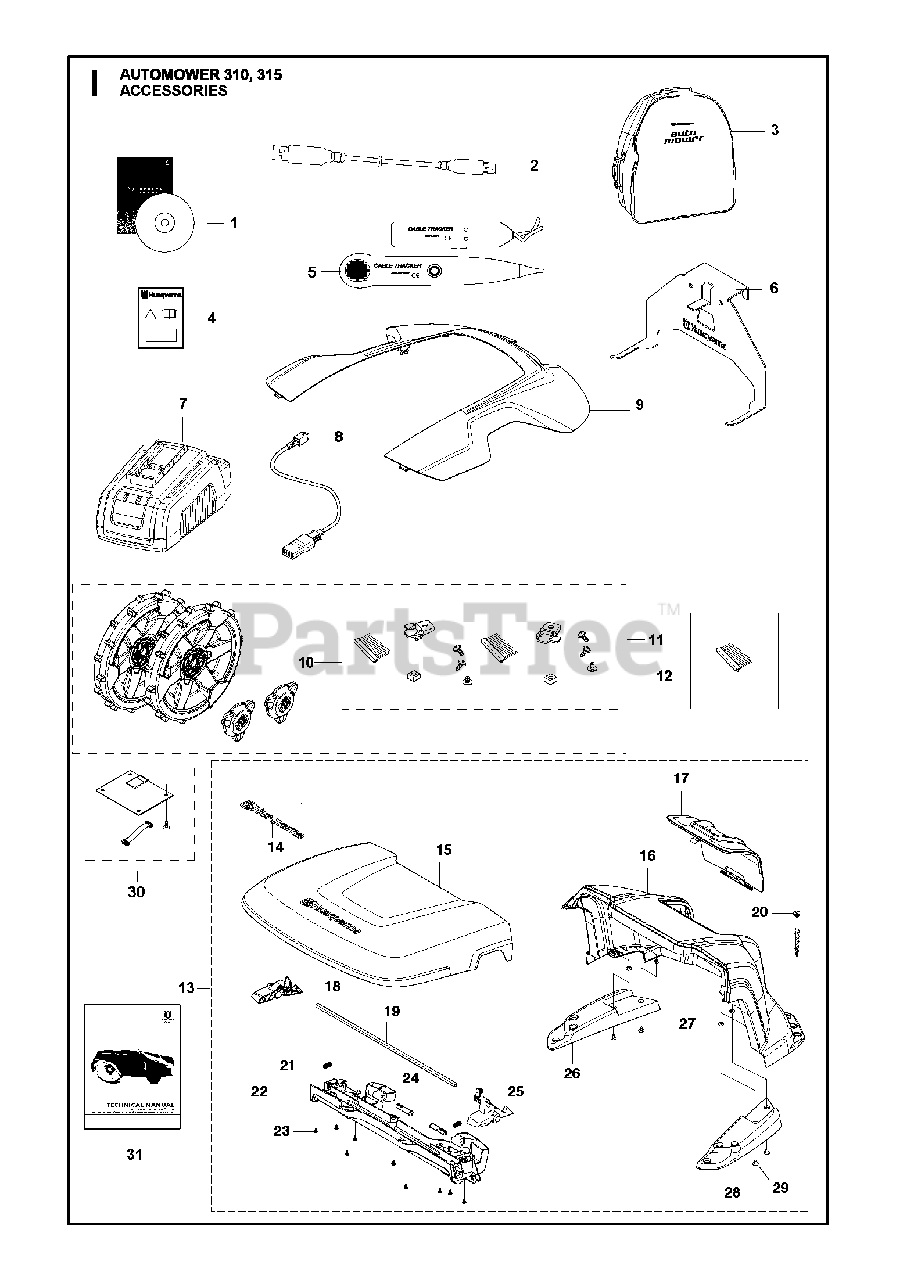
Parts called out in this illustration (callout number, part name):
1	DVD Autocheck, Exp Ser
2	CABLE WHITE ALT GREY
3	BAG
4	LABEL WARRANTY SEAL DEALER
5	TEST EQUIPMENT
6	315 WALL HANGER
7	CHARGER BATTERY TEST
8	CABLE ASSY QUICK CHARGER
9	GREY COVER
9	Cover, White
9	ORANGE COVER
10	WHEEL BRUSH KIT 315
11	WHEEL KIT AM310315. H
12	BRUSH WITH CARTON
13	HOUSE KIT FOR 315
14	DECAL.HUSQVARNA.210MM
15	COVER LID 315
16	COVER BASE P15
17	HATCH
18	HANDLE RELEASE LEFT
19	ROD
20	SCREW KIT CS
21	SPRING SPRING CAP
22	BEAM
23	SCREW 14MM
24	HINGE PIN
25	HANDLE RELEASE RIGHT
26	SUPPORT BASE LEFT
27	NUT
28	SUPPORT BASE RIGHT
29	SCREW IHPANM M6X25 4.6 ZP-BC
30	GPS MODULE 315 430X
